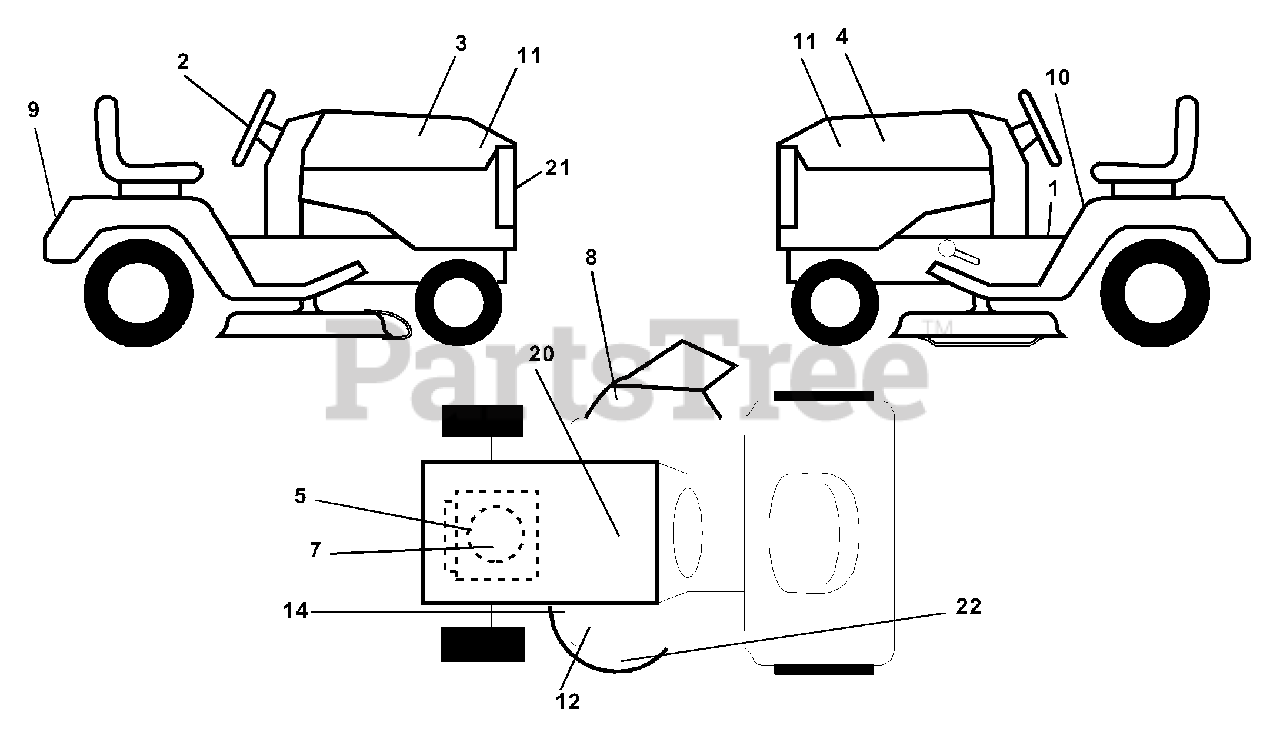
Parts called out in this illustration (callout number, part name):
1	Decal Oper Inst Hyd E/F
2	Decal Strg Wheel Logo
3	Decal Hood RH
4	Decal Hood LH
5	Decal Engine
7	Decal Engine Recoil Cover
8	Decal Warning
9	Decal Fender Husq
10	Decal Fender Danger E/F
11	Decal Hood Sides
12	Decal Clutch/Brake
14	Decal V-Belt Schematic
20	Decal Bat Dan/Psn
21	Decal Grille Husq
22	Decal Deck Caution Prem 48
